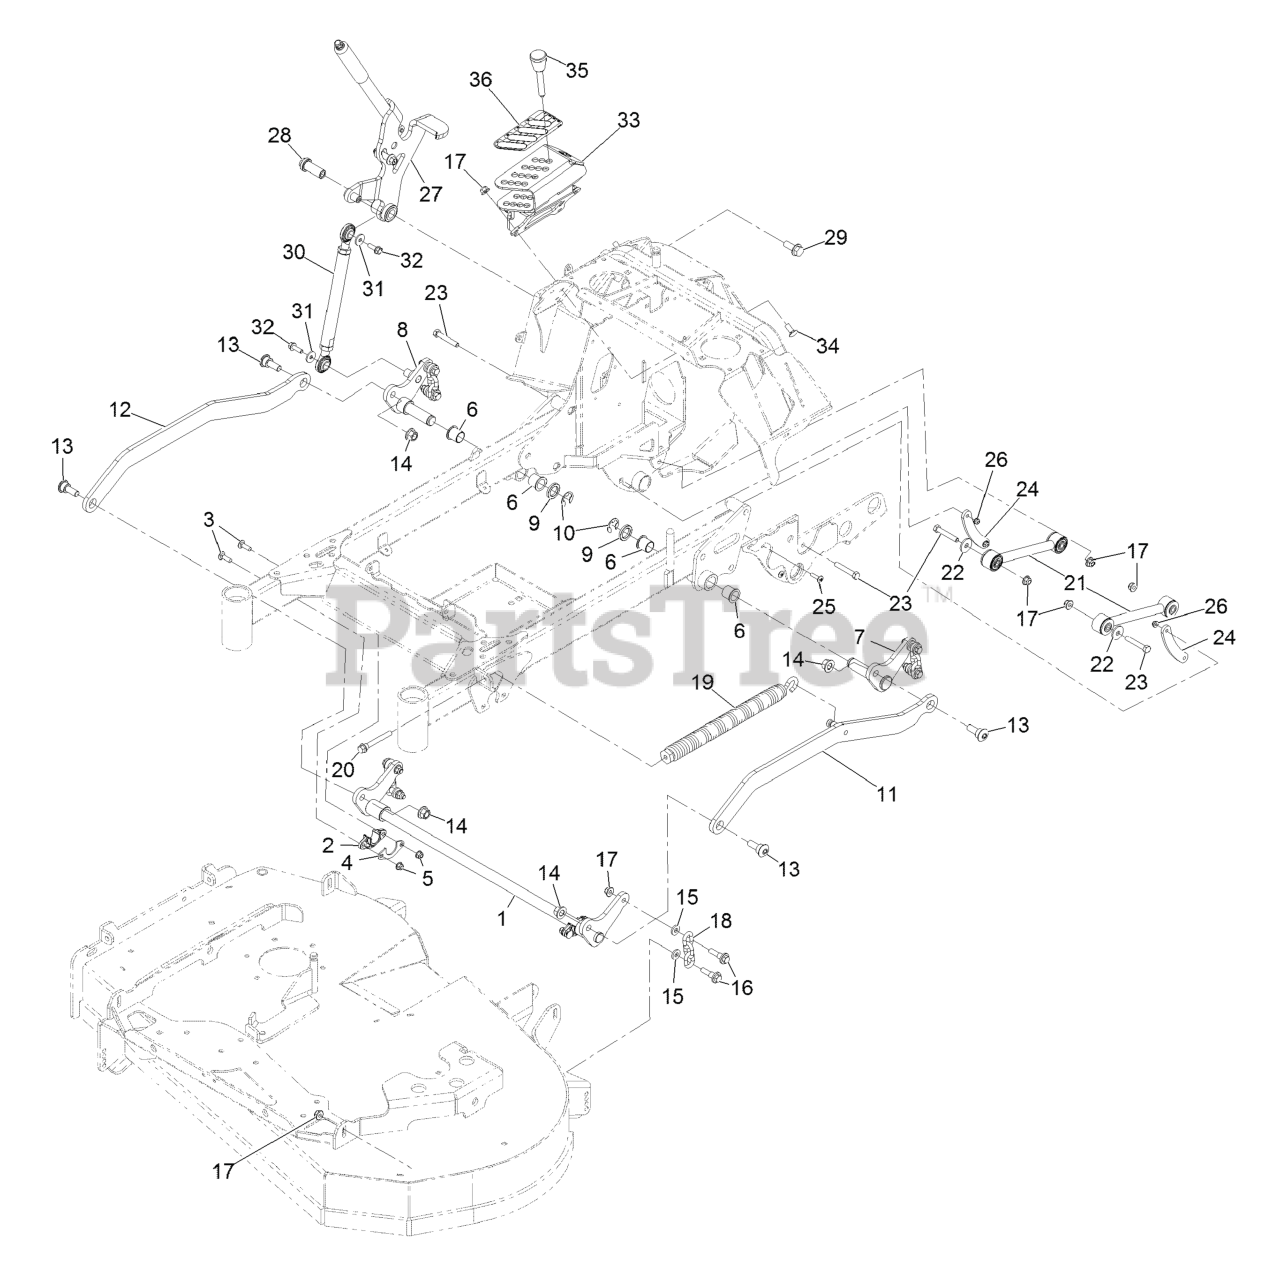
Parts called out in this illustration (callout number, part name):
1	WELD, HOC LIFT SHAFT
2	BUSHING-FLANGE
3	BOLT-CARR
4	GUSSET-LIFT, DECK
5	NUT-HF, NI
6	BUSHING, IGUS
8	WELD, BELLCRANK, RT RR
9	SPACER, HOC PIVOT
10	RING-RETAINING, EXT
11	WELD, LIFT STRAP, LT
12	STRAP, LIFT, RT
13	BOLT, SHOULDER
14	Nut-Lock 1/2-13
16	BOLT-SHOULDER
17	NUT-HF, NI
18	CHAIN-DECKLIFT
19	SPRING-EXTENSION
20	BOLT-SHOULDER
21	ASM, STRUT W/ BUSHINGS
22	WASHER
23	SCREW-HH
24	STRIP, RUB
25	SCREW-TTH
27	ASM, HOC LEVER
28	PIVOT, HOC LEVER
29	SCREW-HHF
30	ASM, LIFT ROD
31	WASHER-FRICTION
32	Screw-HHF
33	WELD, HOC INDEX
34	SCREW-CARR
35	PIN-HOC
36	DECAL-HEIGHT OF CUT
